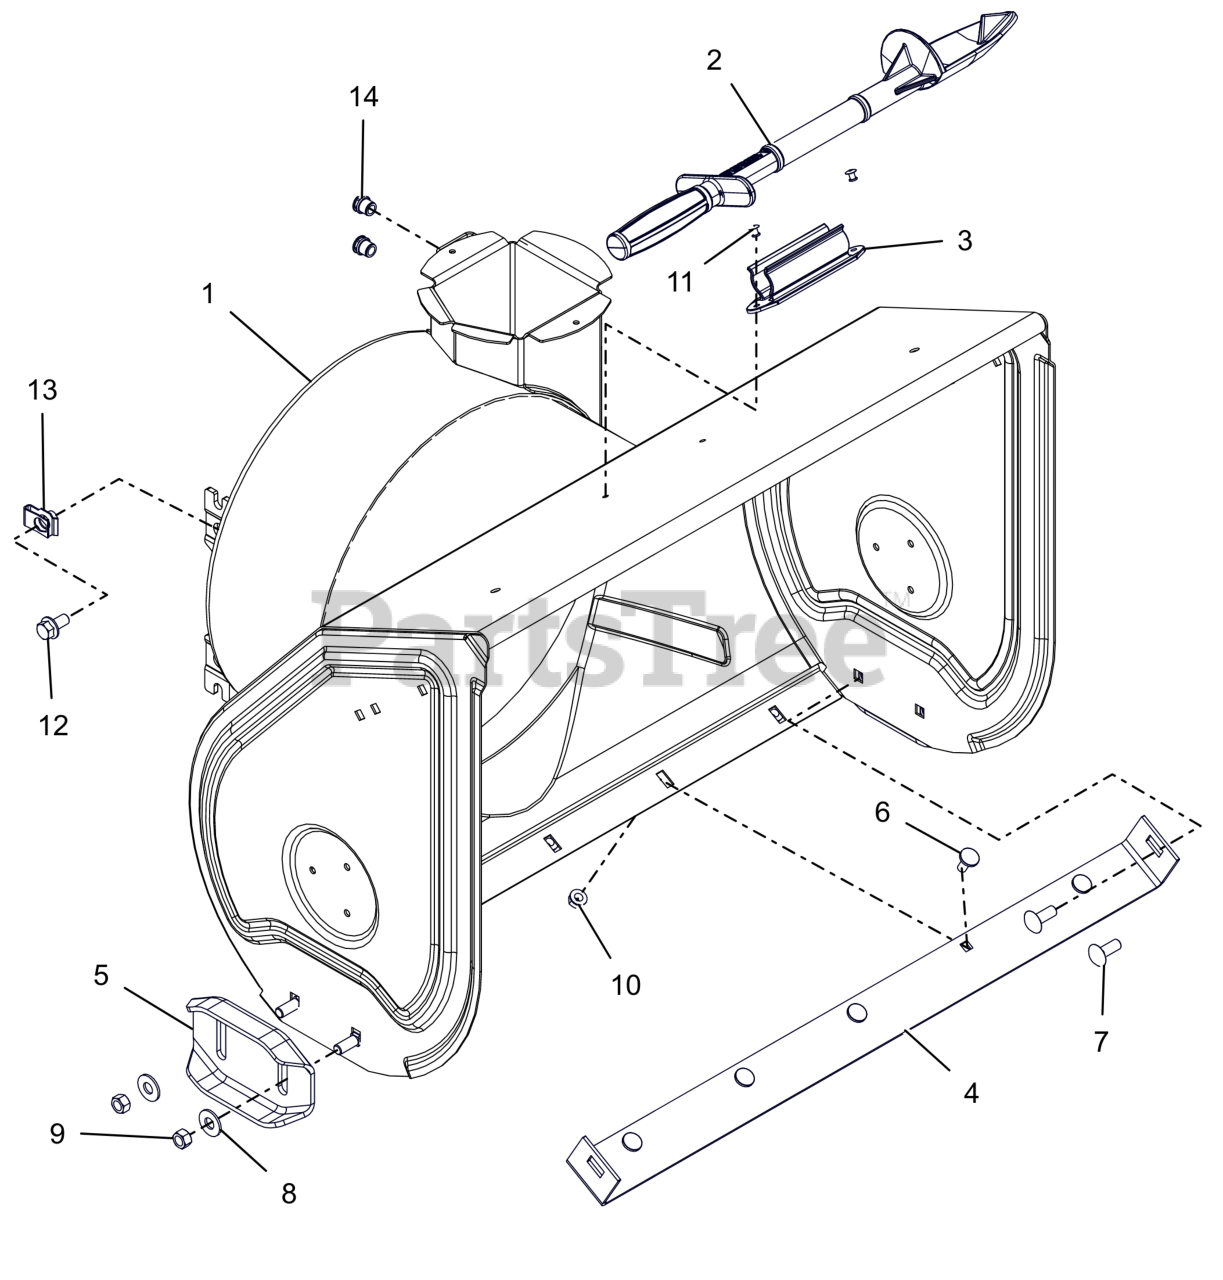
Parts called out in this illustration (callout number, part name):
1	BLOWER HOUSING W/DECAL 28"
2	DEVICE, SNOW CLEAN OUT
3	MOUNT, SNOW CLEAN OUT
4	BLADE, SCRAPER - 28"
5	SKID SHOE, REVERSIBLE - ORANGE
6	BOLT, MODIFIED HEAD CARRIAGE
7	BLT,RHSSN .38-16X1.00 G5 ZCC
8	WSHR,FLT .438X1.00X.083 ZCC
9	NUT-LK-CTR .38-16 ZC120
10	NUT-LK-TOP-FLG .312-18 GF ZCC
11	RVT, POP .1875 ZCC
13	NUT-RTNR .375-16X.37
14	NUT,THD,INSERT .38-16 ZC120
